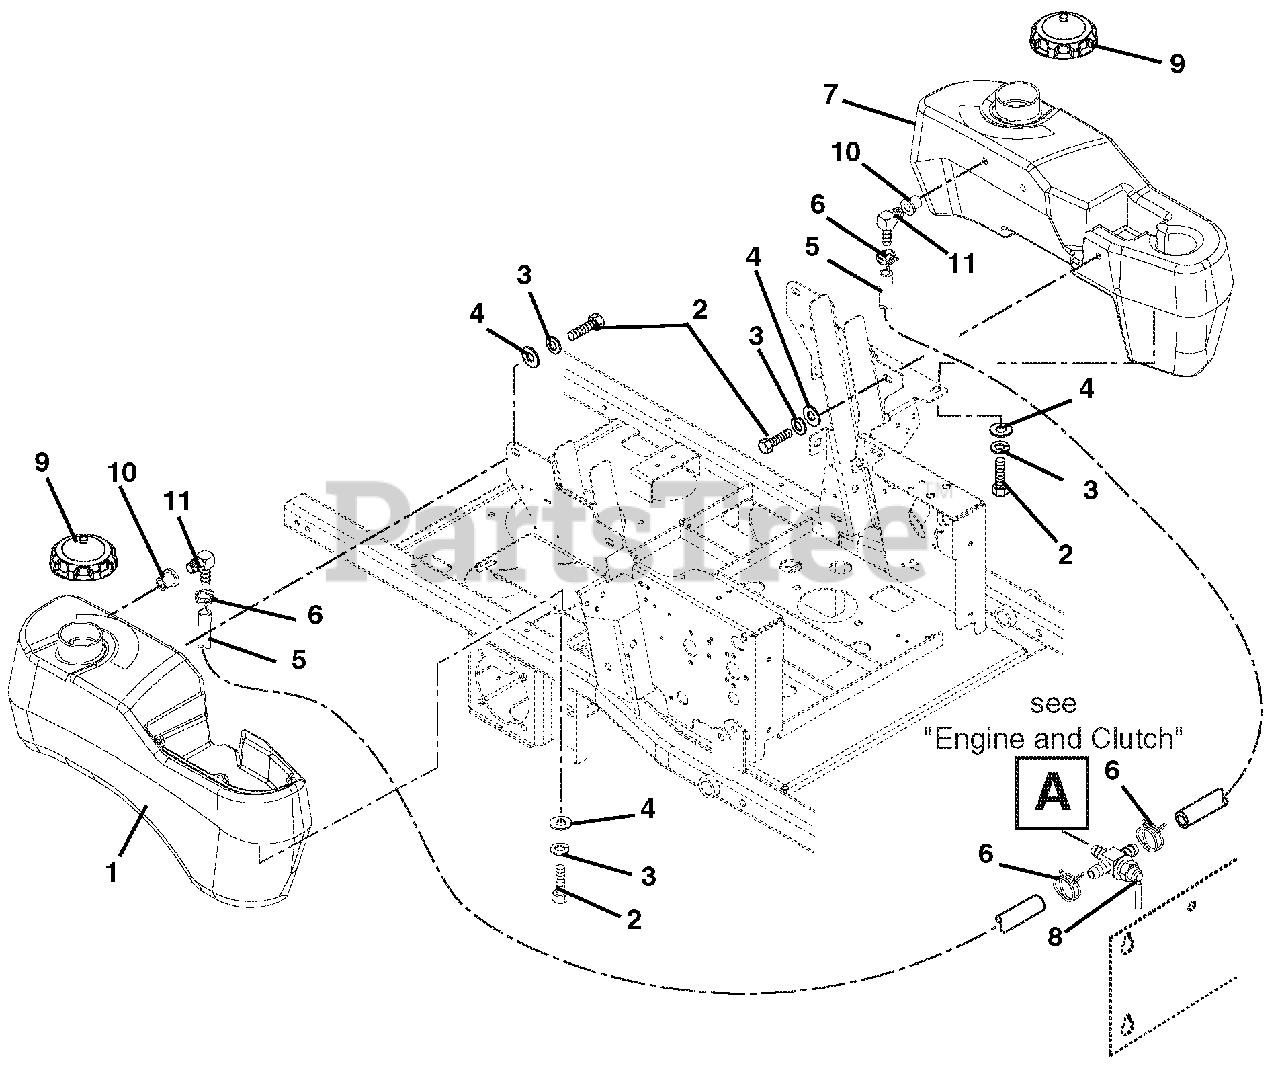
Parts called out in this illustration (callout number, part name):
1	Tank, Fuel - Right Hand
2	Bolt, Hex .31-18 x .75 Grade 5
3	Washer, Locking .31 x .078
4	Washer, Flat Steel .38 x .875 x .083
5	Gas Line, Bulk .25 I.D. (2 @ 63 in.)
6	Clamp, Hose Wire .49/.51 x .116
7	Tank, Fuel Left Hand
8	Valve, Fuel
9	Cap, Gas
11	Tank Fitting
